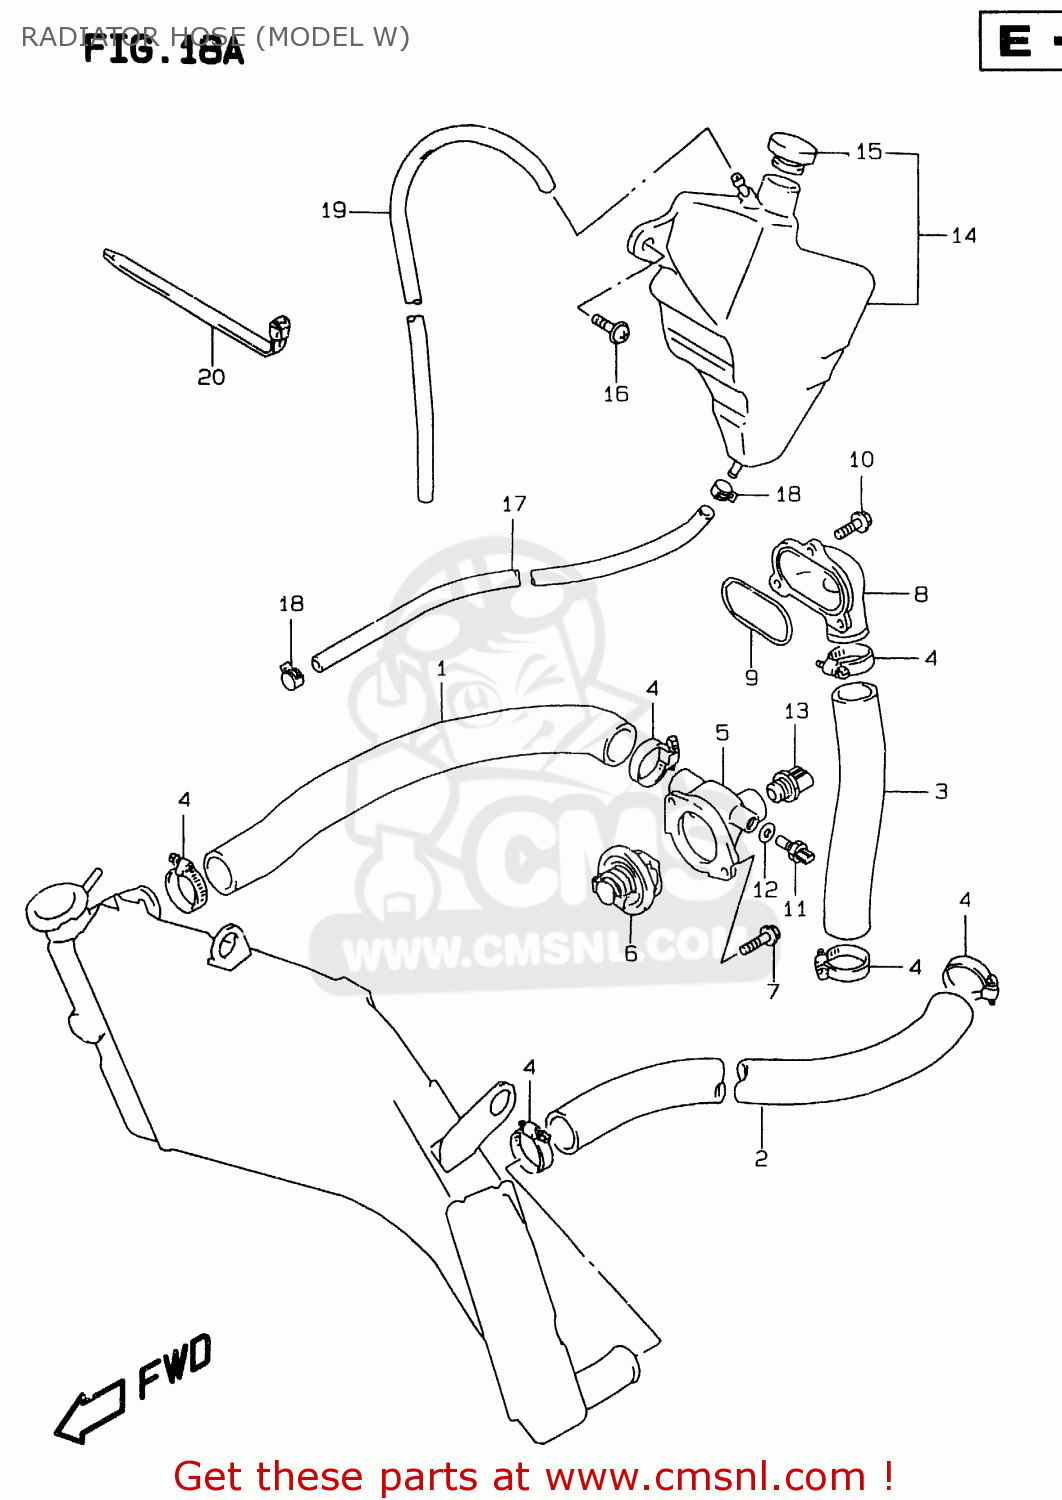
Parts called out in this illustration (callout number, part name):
1	HOSE,RADIATOR INLET
2	HOSE,RADIATOR OUTLET
3	HOSE,CYLINDER INLET
4	CLAMP
5	CAP,THERMOSTAT
6	THERMOSTAT,WATER
7	BOLT
8	CONNECTOR,CYLINDER WATER,INTAKE
9	O RING,CYL WATER CONNECTOR
10	BOLT
11	SENSOR,WATER TEMP
12	GASKET(12.2X21X0.8) (NAS)
13	SWITCH,RADIATOR FAN
14	TANK ASSY,RESERVOIR
15	CAP,RESERVOIR TANK
16	SCREW(6X20)
17	HOSE,RESERVOIR TANK INLET
18	CLIP
19	HOSE,RESERVOIR TANK OUTLET
20	CLAMP L:165
